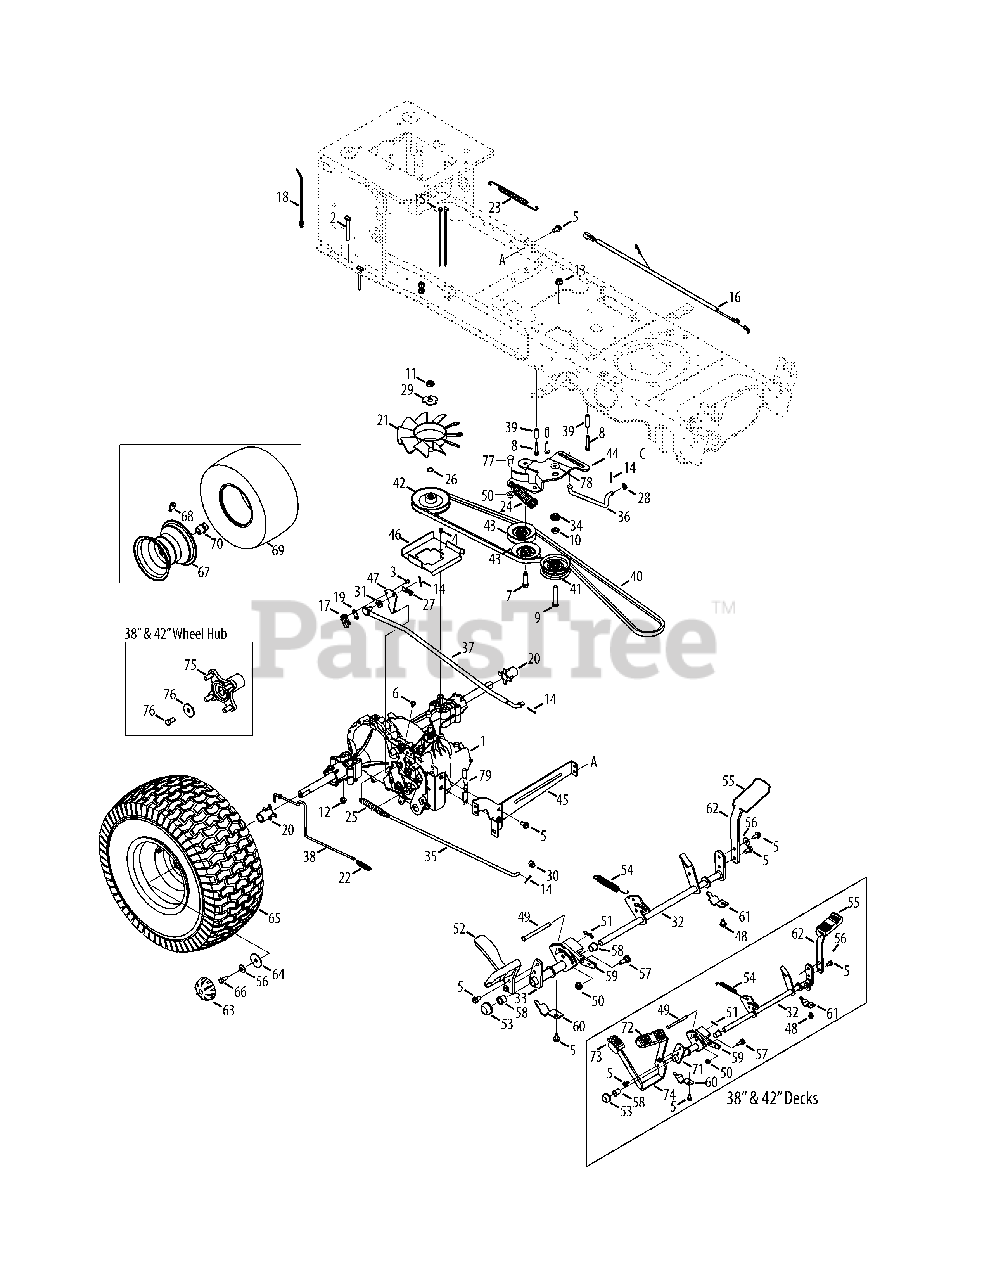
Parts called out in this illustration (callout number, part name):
1	Hydro Transmission
2	Hex Screw, 5/16-18:2.75
3	Screw, #8-18:0.500
4	Screw, #10-16:0.500
5	Taptite Screw, 5/16-18:.750
6	Taptite Screw, 1/4-20:0.375
7	Screw, Sems, 3/8-16, 1.500
8	Taptite Screw, 1/4-20:1.625
9	Hex Screw, 3/8-16:2.25
10	Jam Nut, 7/16-20
11	Nut, Jamlock, 1/2-20
12	Flangelock Nut, 5/16-18
13	Flangelock Nut, 3/8-16
14	Cotter Pin, 3/32:1.0
15	Cable Tie, 3/16 X .05 X 7.4
16	Jumper Harness
17	Short Spring Switch
18	Push Mount Cable Tie 7.5 LG
19	Insulator Nut Plate
20	Sleeve, .765 ID x 1.500 LG, 46"
21	Hydro Fan
22	Extension Spring, .48 OD X 2.03
23	Extension Spring, .500 DIA X 12.6 LG
24	Extension Spring, 1.00 DIA X 4.75
25	Extension Spring, .59 OD X 4.00 LG
26	Wire Ring
27	Extension Spring, .375 OD X 1.44 LG
28	Washer, Flat, .330 X .630 X .0635
29	Washer, Lock, TRANS HYDRO
30	Washer, Flat, .344 X .750 X .120
31	Washer, Flat, .407X.812X.135:HT
32	Brake Control Assembly, 46"
33	Hydro Pedal Bracket Assembly
34	Spacer, Shoulder, 1.375 X .380 X .183
35	Rod, Brake, Hydro
36	Rod, Transmission, Footpedal Bypass
37	Rod, Control, Hydro
38	Rod, Hydro Bypass
39	Spacer, .260 X .372 X 1.420 LG
40	Belt, V Type, Poly
41	Pulley, Idler, Flat 2.75 OD
42	Pulley, Input, 4.13 DIA
43	Pulley, Idler, V-Type x 3.06
44	Bracket, Idler, Center Double
45	Bracket, Mount, Hydro
46	Bracket, Support, Belt Disengage
47	Switch Actuator Bracket
48	Taptite Screw, 5/16-18:0.625
49	Clevis Pin, 5/16 x 3.985
50	Flangelock Nut, 3/8-16
51	Bow-Tie Cotter Pin
52	Control Pedal
53	Push Cap
54	Extension Spring, .63 DIA x 4.95 LG
55	Brake Pedal Pad
56	Washer, Bell, .340 x .872 x .060
57	Shoulder Bolt, .500 x .270:3/8-16
58	Flange Bearing, .630 ID x .695 OD x .60
59	Cruise Latch
60	Pedal Support Bracket
61	Pedal Support Bracket, 5/8
62	Brake Pedal Bracket
63	Hub Cap
64	Washer, Flat, .350 x 1.59 x .062
65	Wheel Assembly
66	Hex Screw, 5/16-24 x .750
67	Rim Assembly, Plastic Bead, 46"
68	Tubeless Air Valve
69	Tire, 20 x 8 x 8, 38" & 46"
70	Axle Hub
71	Hydro Pedal Bracket Assembly
72	Reverse Pedal Pad
73	Forward Pedal Pad
74	Drive Pedal Bracket
75	Wheel Assembly Hub, 38" & 42"
76	Hex Screw, 5/16-24:.750
76	Washer, Bell, .340 x .872 x .060
77	Scr, Shldr, .50 x .685 3/8-16
78	Washer, Flat, .385 x 1.0 x .030
79	Belt Keeper Rod
